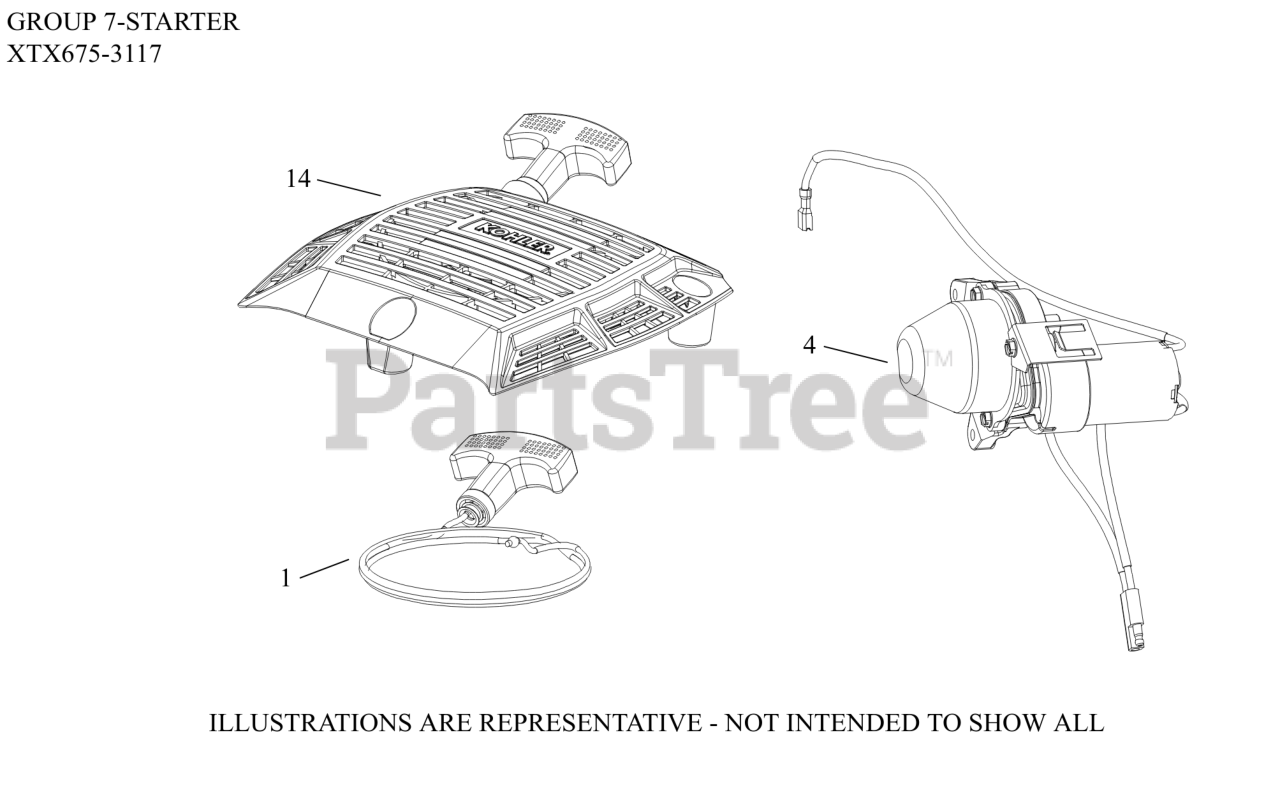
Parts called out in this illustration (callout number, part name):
1	KIT, STARTER ROPE W/HANDLE
4	STARTER ASSEMBLY W/BRAKE
14	STARTER ASSEMBLY, RETRACTABLE
